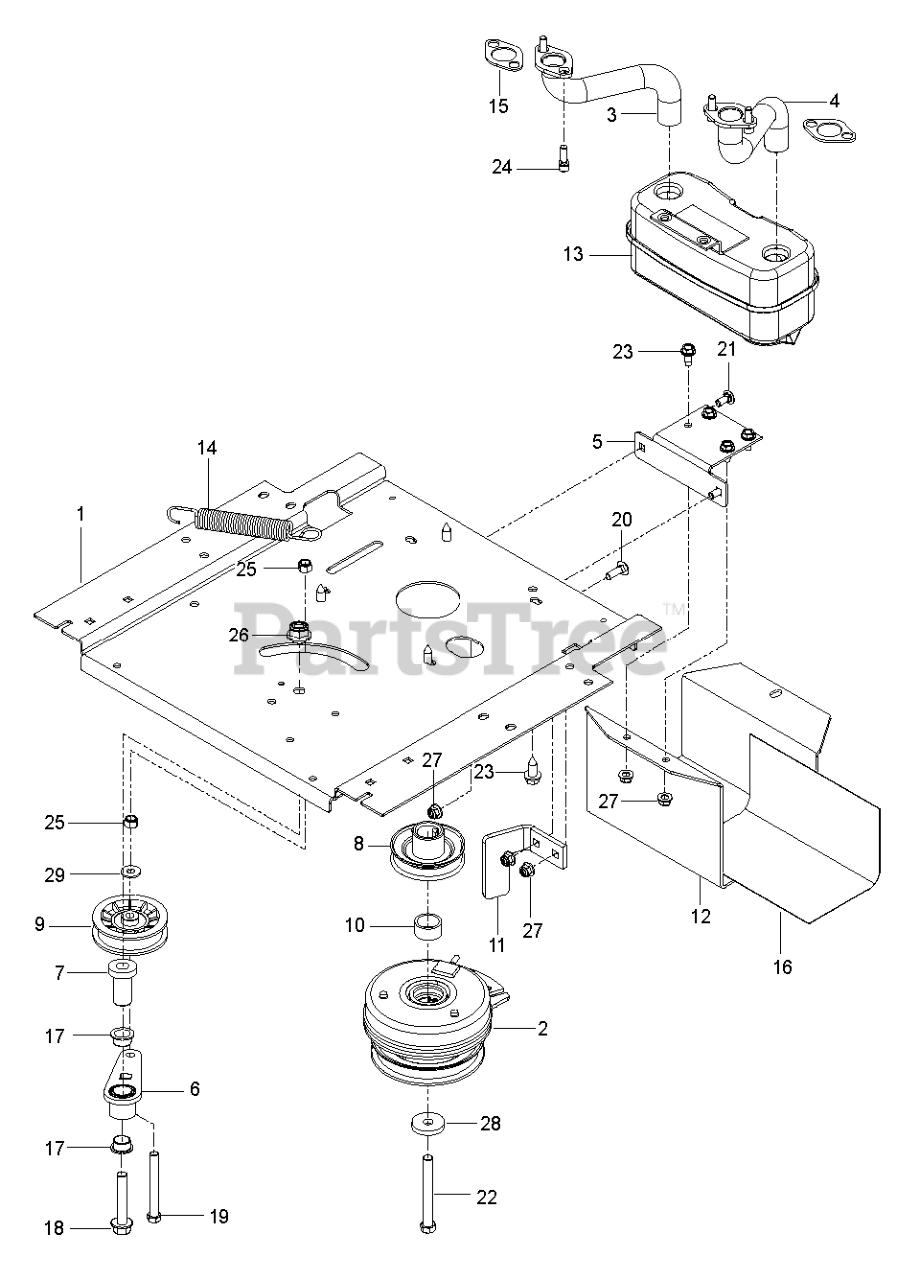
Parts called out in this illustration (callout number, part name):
1	RB CTRL.AW2.22+RGD.BS.GRY/BLK
9	CABLE.CONTROL.22RGD.GEN2
10	BRACKET.DRIVE.CONTR.GEN2.BLACK
11	SCREW.HX.13X.750
12	NUT.HEX.1/2-20
13	RP TRANSMISSION.22+.RGD.AW2/
15	WASHER.FLAT.1/2
16	ROD.CONNECTING.RGD.22+.HW.BLAC
17	NUT.LOCK.5/16-18
18	KIT.SEL.ASM.22+HI-WHEEL.ZINC
19	KNOB.SEL.SPRING.22+.SP.RIB.BLK
20	COVER.BELT.22.RGD
21	SCREW.PLASTIC.ANCHOR.5/16
23	ADJUSTER.ARM.ASM.AX.LT.SP.HW
24	BRACKET.WHL.ADJ.9.POS.W/PAD
25	BRACKET.DRIVE.COVER.RGD.BZP
26	BRACKET.TRANS.BELT.KEEPER.BZP
28	E-RING 7/16 RE
29	COVER.DUST.WHEEL.RGD.HW
30	BOLT.5/16HEX.WHS.HD
31	PAWL, DRIVE
32	WHEEL.11.ALPHA.GRY.EXT*
33	NUT.HEX.FLANGE.3/8-16.LO(3 2)
34	O-RING..070X.487.NEOPRENE
35	AXLE.REAR.RGD
36	AXLE.ASM.FRONT.RGD.CLEAR.ZINC
38	NUT.HEX.FLANGE.1/4
39	SHOULDER BOLT SEMI GIMLET PT.
40	WHEEL.8".GRAY.HUSQ.BUSHING.CEN
41	PINION.12.TEETH.RGD.22+HW
44	BELT.DRIVE.RGD.PLUS
48	KIT.WASH-OUT.PORT.ZINC.WALK
49	WASHOUT.PORT.ZINC.RGD.22+
50	WASHER.LOCK.INTERNAL.TOOTH
51	LOCKNUT.HEX.WITH.O-RING
56	HUBCAP.H.3SPK.GREY
57	NUT.HEX.FLANGE.3/8-16.LOCKNUT
58	SCREW.12-14X1.500
59	BRACKET.SUPPORT.22+RWGD.BZP
61	SCREW, PHILLIPS HEAD 10 X 5/8
62	CLIP.CABLE.BLK
63	FASTENER.PUSH.O.250X0.783
84	COUPLING.QUICK CONNECT
85	BRACKET.FRT.AXLE.SUPPORT
